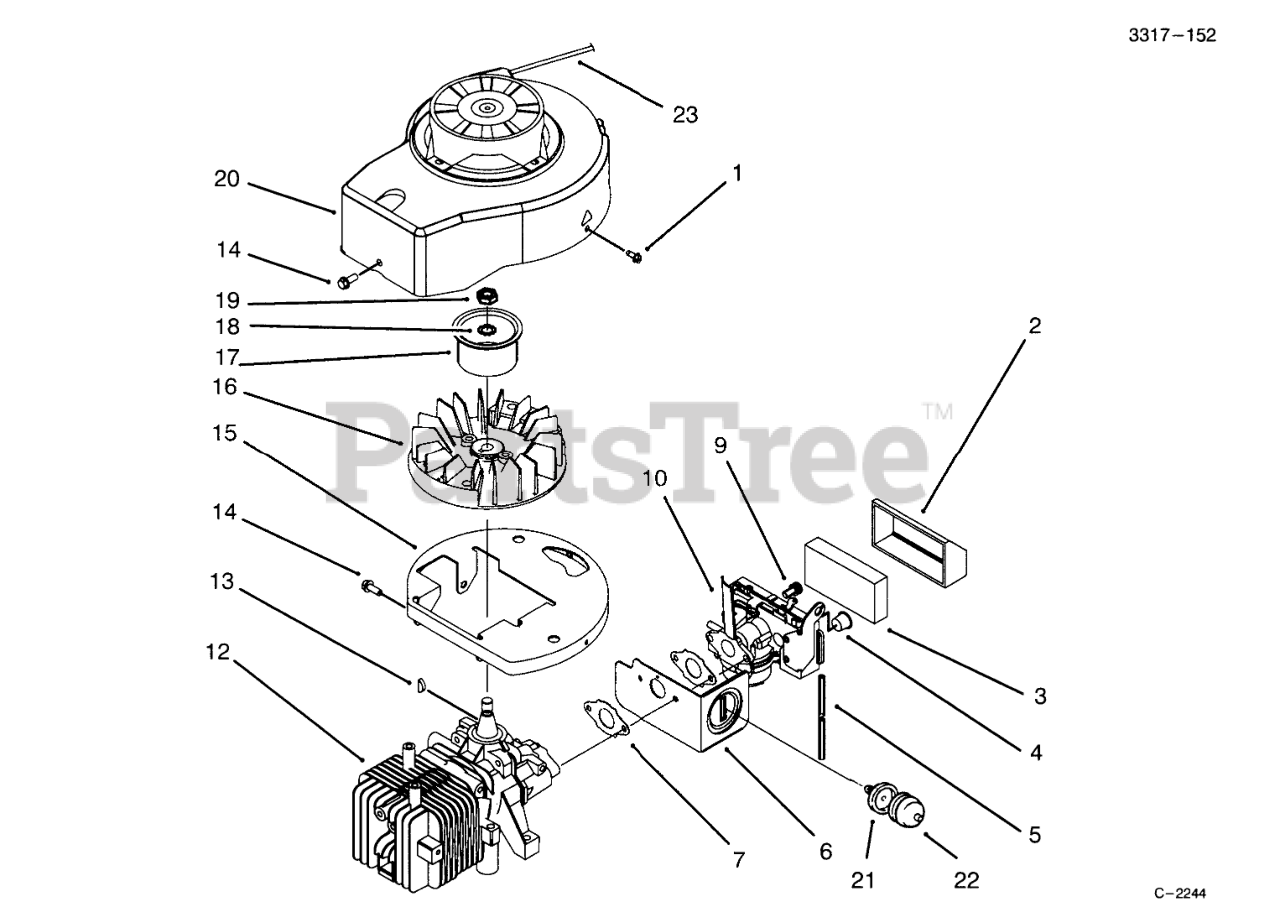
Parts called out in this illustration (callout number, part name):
1	SCREW VF
2	COVER-AIR FIL. V
3	ELEMENT-AIR FIL VF
4	SHIELD-FUEL V
5	Hose-Primer
6	SHIELD - CARB. V
7	GASKET-CARB VF
9	SCREW
10	Carburetor Assembly
12	Short Block Assembly
14	SCREW
15	Base-Shroud
16	FLYWHEEL(MACH) V
17	HUB-STARTER V
18	WASHER-LOCK
20	SHROUD/START
21	BODY-PRIMER
22	BULB-PRIMER
23	ROPE - GREY 88 5/8
